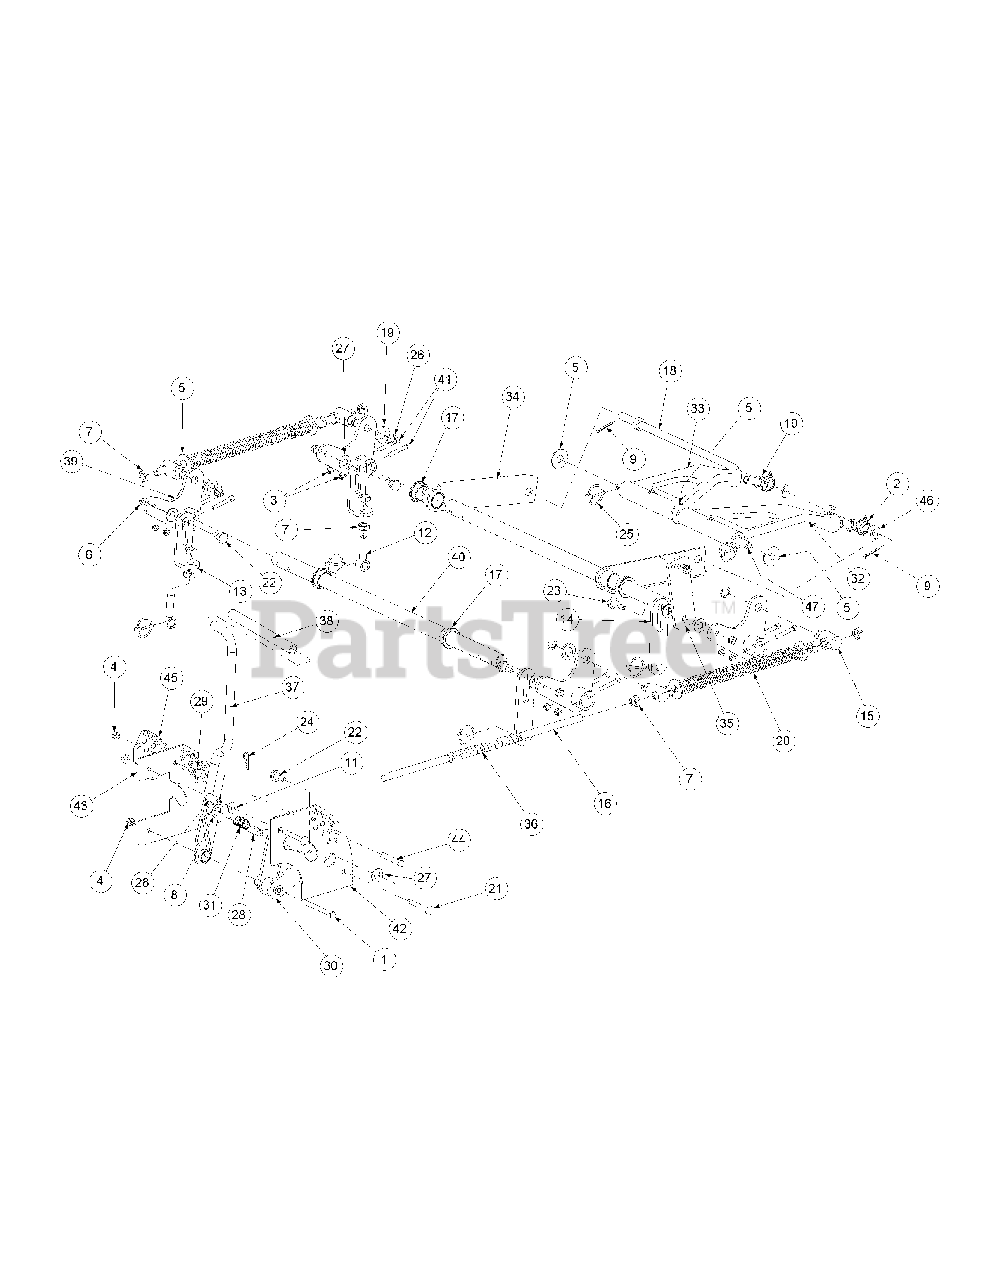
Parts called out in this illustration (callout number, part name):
1	Hex Cap Screw, 3/8-16, 3.75
2	Rod End, Male
3	Nut, 5/16-18, Nylock
4	Nylock Insert Lock Nut, 3/8-16
5	Flat Washer, 5/8
6	Hex Nut, Flange Lock, 3/8-16
7	Jam Nut, 5/8-11
8	Flat Washer, .06, .776, 1.25
9	Cotter Pin, 3/16 x 1-1
10	Jam Nut, 5/8-18
11	Idler Washer
12	Eye Bolt, 5/8ID
13	Eye Bolt Mount Link, 5/8 ID
14	Deck Link
15	Ferule Lift
16	Lift Connector Rod
17	Hex Flange Bearing, 1.25 ID
18	Front Lift Link, Rod Mount
19	Spacer, .812 ID x .268 Lg.
20	Lift Compression Spring
21	Carriage Bolt, 3/8-16, 2.75
22	Shoulder Screw, 0.625 OD x .437 Lg.
23	Shoulder Screw, 0.625 OD x .830 Lg.
24	Cotter Pin, .148 x 3.00
25	Linch Pin, 3/16 Dia.
26	E Clip, 3/4 Dia.
27	Nylon Flat Washer, 5/8
28	Spacer, .39 ID x .63 OD x 1.442
29	Shoulder Screw, .50 OD x 0.27
30	Lift Pivot Assembly
31	Lift Handle Spring
32	Bearing Lift Brace Assembly, Right Hand
33	Bearing Lift Brace Assembly, Left Hand
34	Front Frame Strut Assembly
35	Lift Link Adjustment
36	Hose, 5/8 ID 13/16 OD, 8" LG
37	Lift Handle Assembly
38	Lift Handle Grip
39	Bellecrank Weldment Assembly
40	Deck Lift Shaft
41	Socket Head CapScrew, 5/16-18 x 2
42	Outer Lift Index Plate
43	Inner Lift Index Plate
44	Clevis Pin, .438 Dia. x 2.625 Lg.
45	Decal Height Indicator
46	Spacer, .630 ID x 1.06 OD x .440
47	Lift Link Rod
